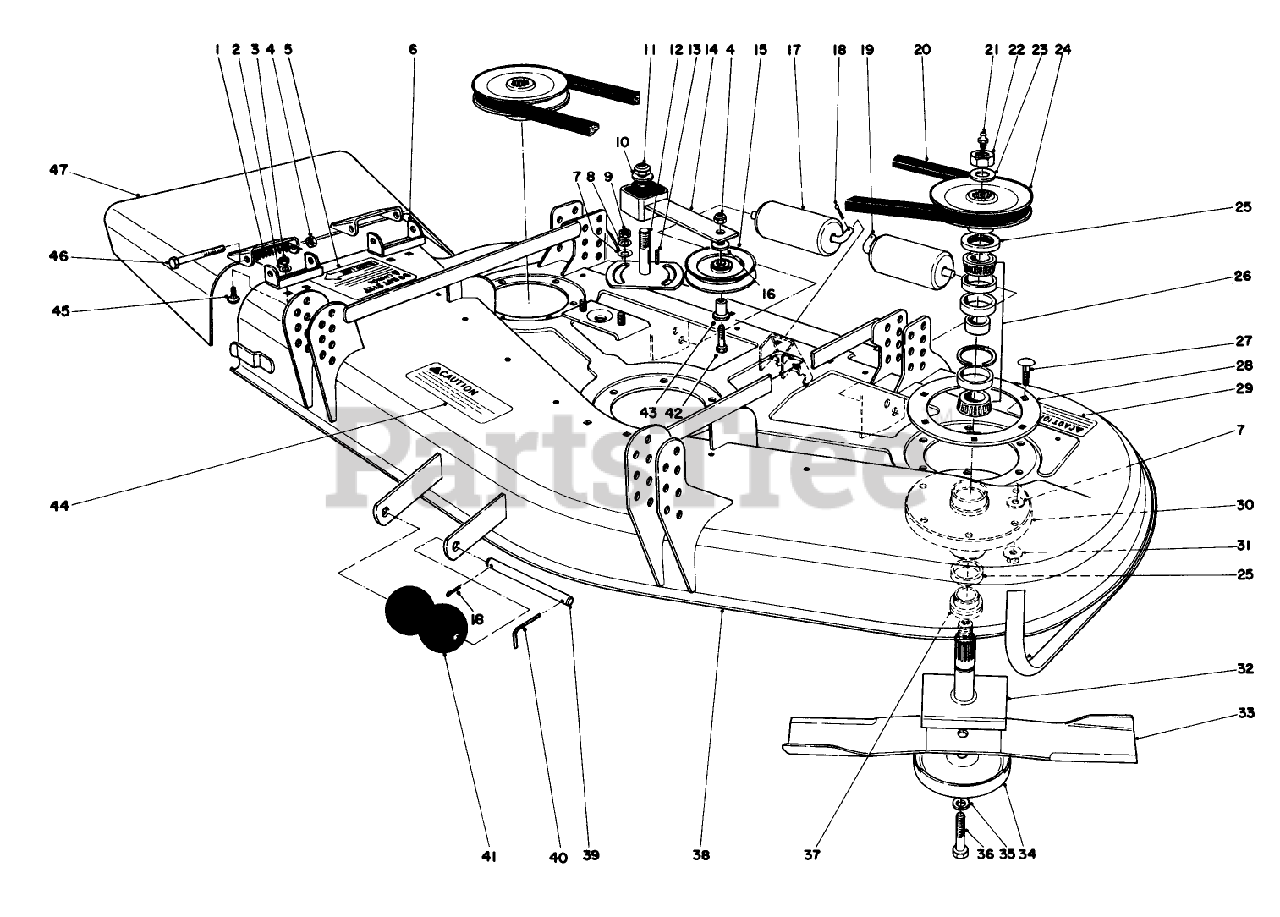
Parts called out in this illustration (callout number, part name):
1	SPRING
2	WASHER-LOCK
3	NUT-HEX
4	NUT-HEX
5	Decal-Caution
6	Bracket-Pivot
7	WASHER-FLAT
8	WASHER-LOCK
9	NUT-JAM
10	WASHER-FLAT
11	NUT-LOCK, NI
12	PLATE-IDLER
13	KEY-SQUARE
14	IDLER ARM ASM
15	PULLEY-IDLER
16	WASHER-FLAT
17	ROLLER-DECK
18	PIN-COTTER
19	SHAFT-ROLLER, REAR
20	V-BELT
21	FITTING-GREASE
22	NUT-HEX
23	WASHER
24	MUFFLER
25	SEAL-OIL
26	BEARING ASM
27	SCREW-CARR
28	SUPPORT-DECK, RING
29	DECAL-CAUTION, BLADE
30	HOUSING-SPINDLE
31	NUT-HF
32	SHAFT
33	Blade
34	Cup-Scalp
35	WASHER-LOCK
36	SCREW-BLADE
37	SPACER
38	GM 52 DECK WA RO
39	SHAFT-ROLLER
40	PIN-SPECIAL
41	ROLLER
42	SCREW-HH
43	BUSHING-PULLEY
44	Decal-Caution
45	SCREW-CARR
46	SCREW-HH
47	Deflector
